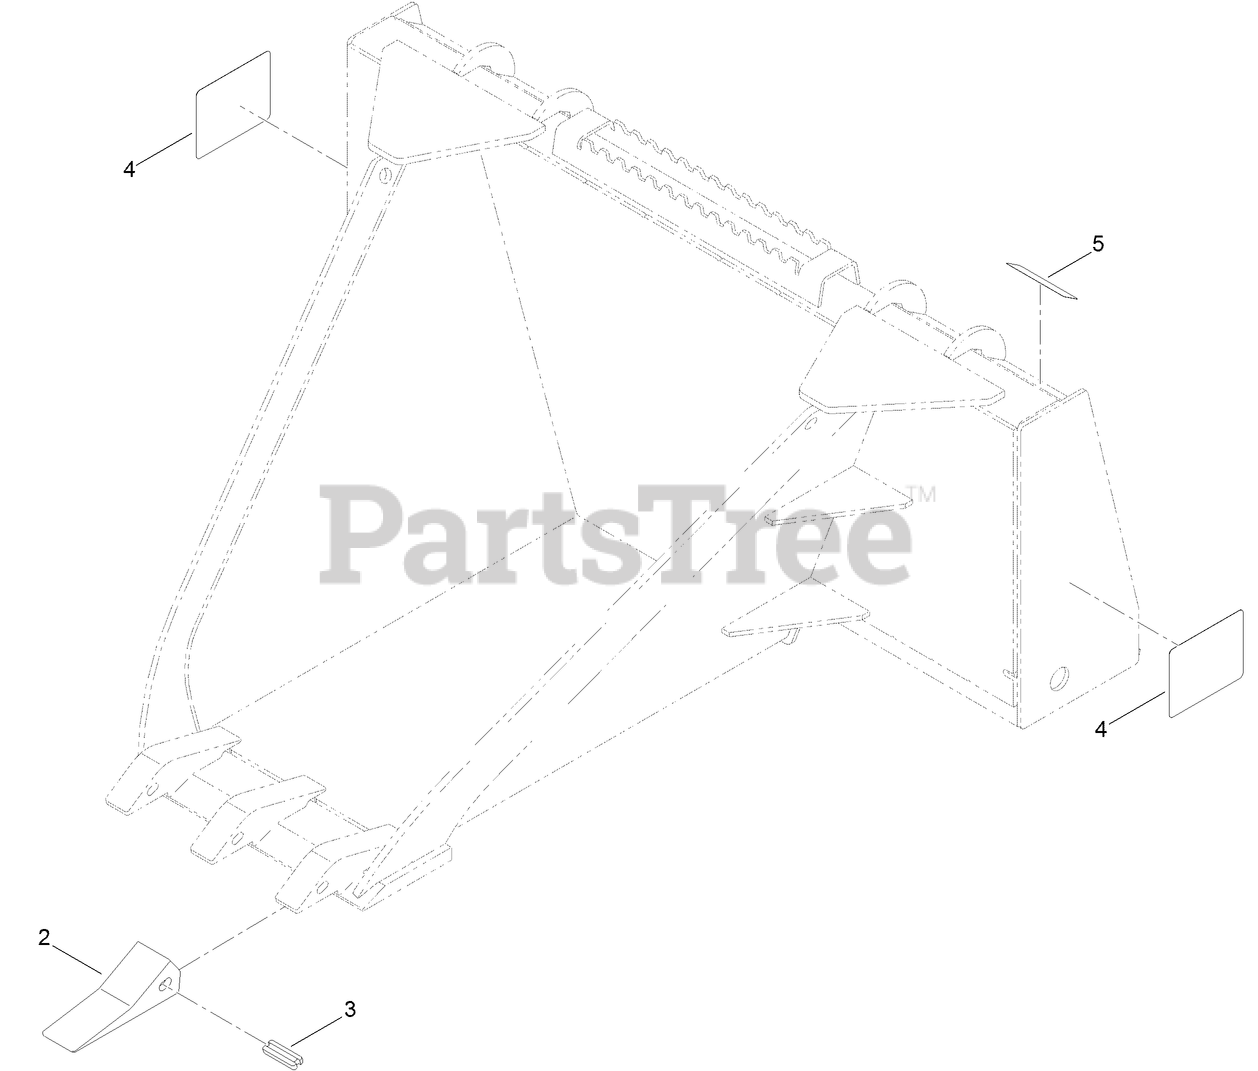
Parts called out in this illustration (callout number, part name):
2	TOOTH-CAST
3	PIN-FLEX
4	DECAL-DANGER
5	DECAL
